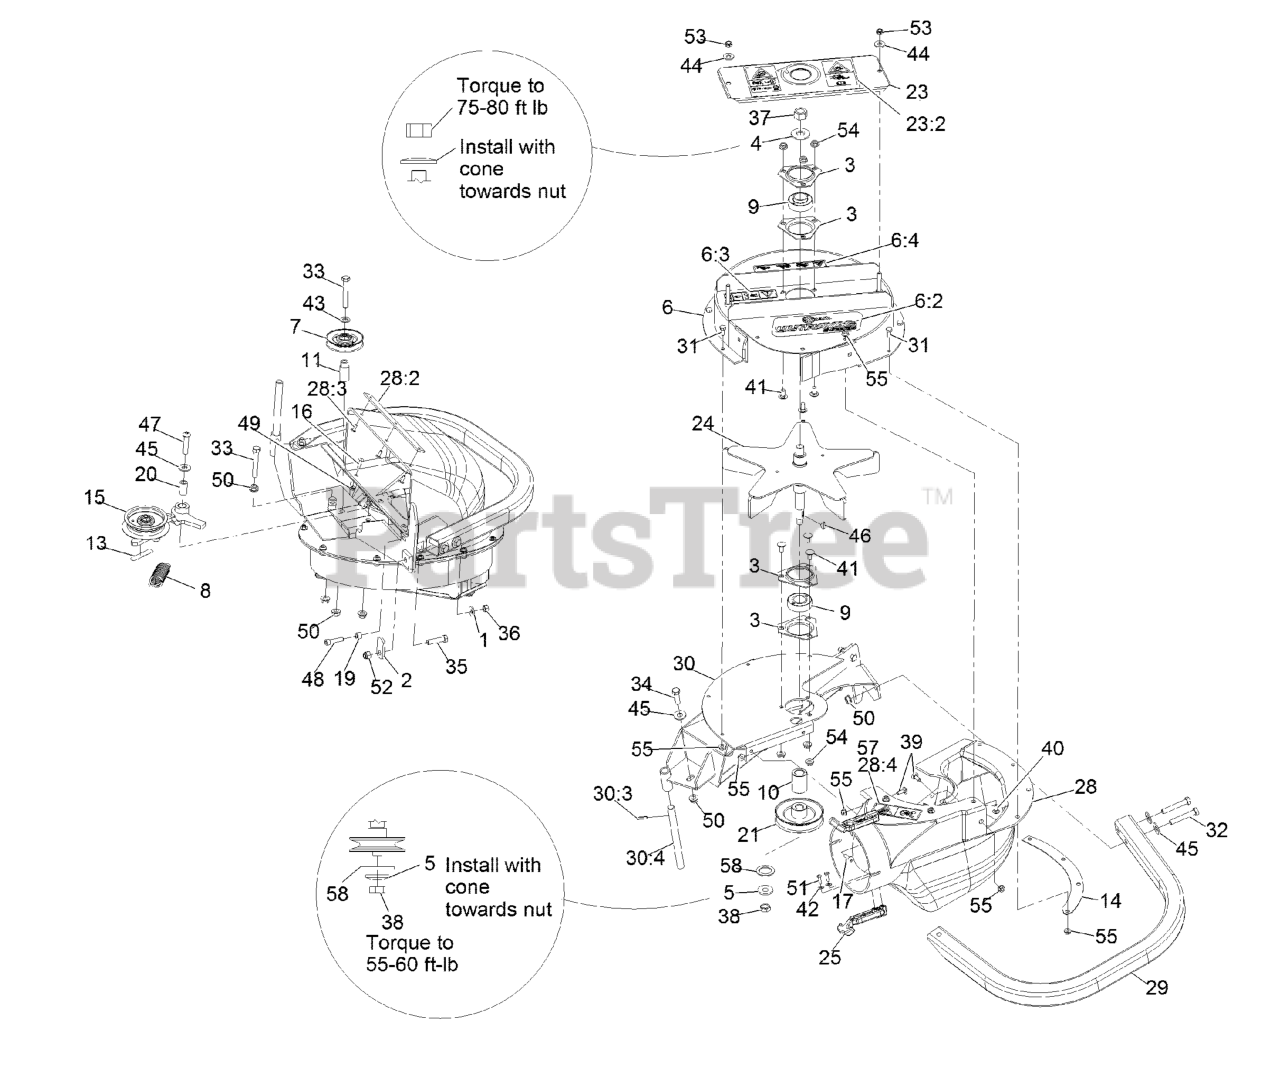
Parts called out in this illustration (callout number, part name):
1	WASHER-SPRING
2	LATCH-CATCHER, GRASS
3	HOUSING-FLANGE
4	WASHER-SPRING
5	WASHER-SPRING
6	ASM-UPPER HOUSING SMALL
6:2	Decal-Ultravac S-Series
6:3	DECAL-COVER, MISSING
6:4	DECAL-WARNING WEIGHT
7	IDLER-INSIDE
8	SPRING-IDLER
9	BEARING
13	DECAL-WARNING
14	PLATE-BACKING, BLOWER
15	ASM, Idler
16	SCREW-HEAD, TRUSS
19	BUSHING, LOCATOR
20	BUSHING-PIVOT, IDLER
21	SHEAVE-BLOWER
23	ASM, BEARING COVER
23:2	Decal-Warning Blower
24	IMPELLER
25	LATCH-RUBBER
28	ASM,BLOWER CHUTE LHP
28:2	PLATE-REINFORCEMENT
28:3	RIVET-BLIND
28:4	Decal-Blower-Impeller Hazard
30	WELD, FRAME SM BLOWER
30:3	PIN-ROLL
30:4	SHAFT-CATCHER, GRASS
31	SCREW-HH
32	SCREW-HH
33	SCREW-HH
34	SCREW-HH
35	SCREW-HH
36	NUT-HEX
37	NUT-HEX
38	NUT-JAM
39	BOLT-CARR
40	SCREW-CARR
41	SCREW-CARR
42	WASHER-FLAT
43	WASHER-FLAT
44	WASHER-FLAT
45	WASHER-FLAT
46	KEY-WOODRUFF
47	SCREW-HSBH
48	SCREW-HSH
50	NUT-HHF, WHIZ
51	SCREW-PPH
52	NUT-LOCK, NI
53	NUT-LOCK, NI
57	Decal-Blower-Impeller Hazard
58	WASHER-SPACER
